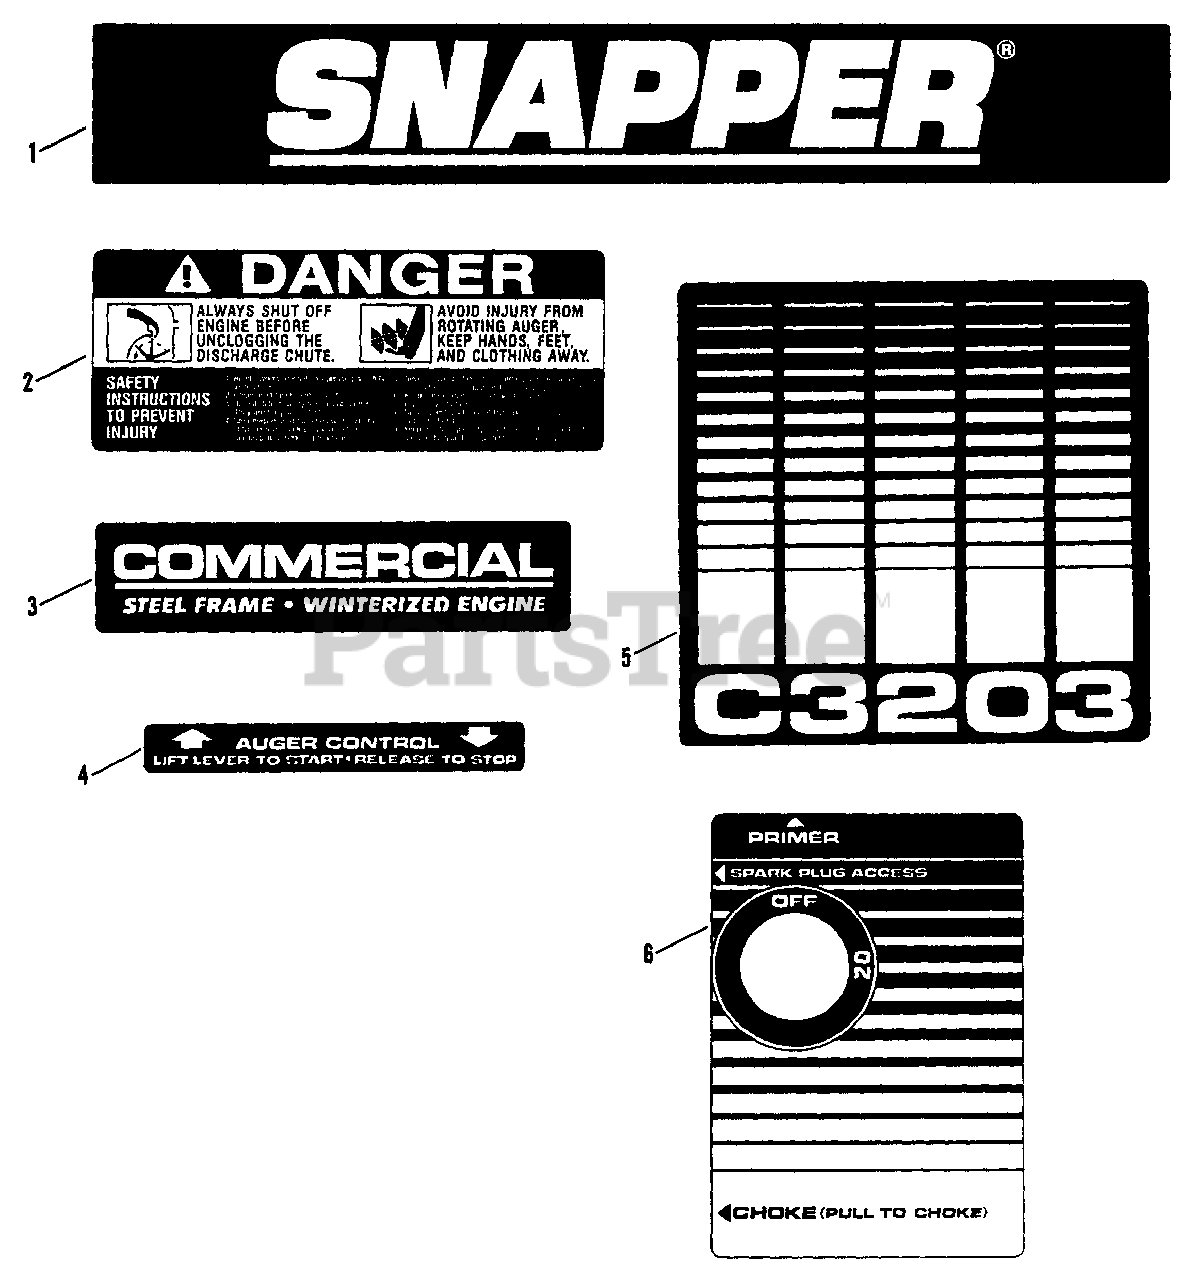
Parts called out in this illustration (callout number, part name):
1	DECAL, SNAPPER
2	DECAL, DANGER
3	DECAL, Commercial
4	DECAL, Auger Control
5	DECAL, Model C3203
6	DECAL, Control Panel
